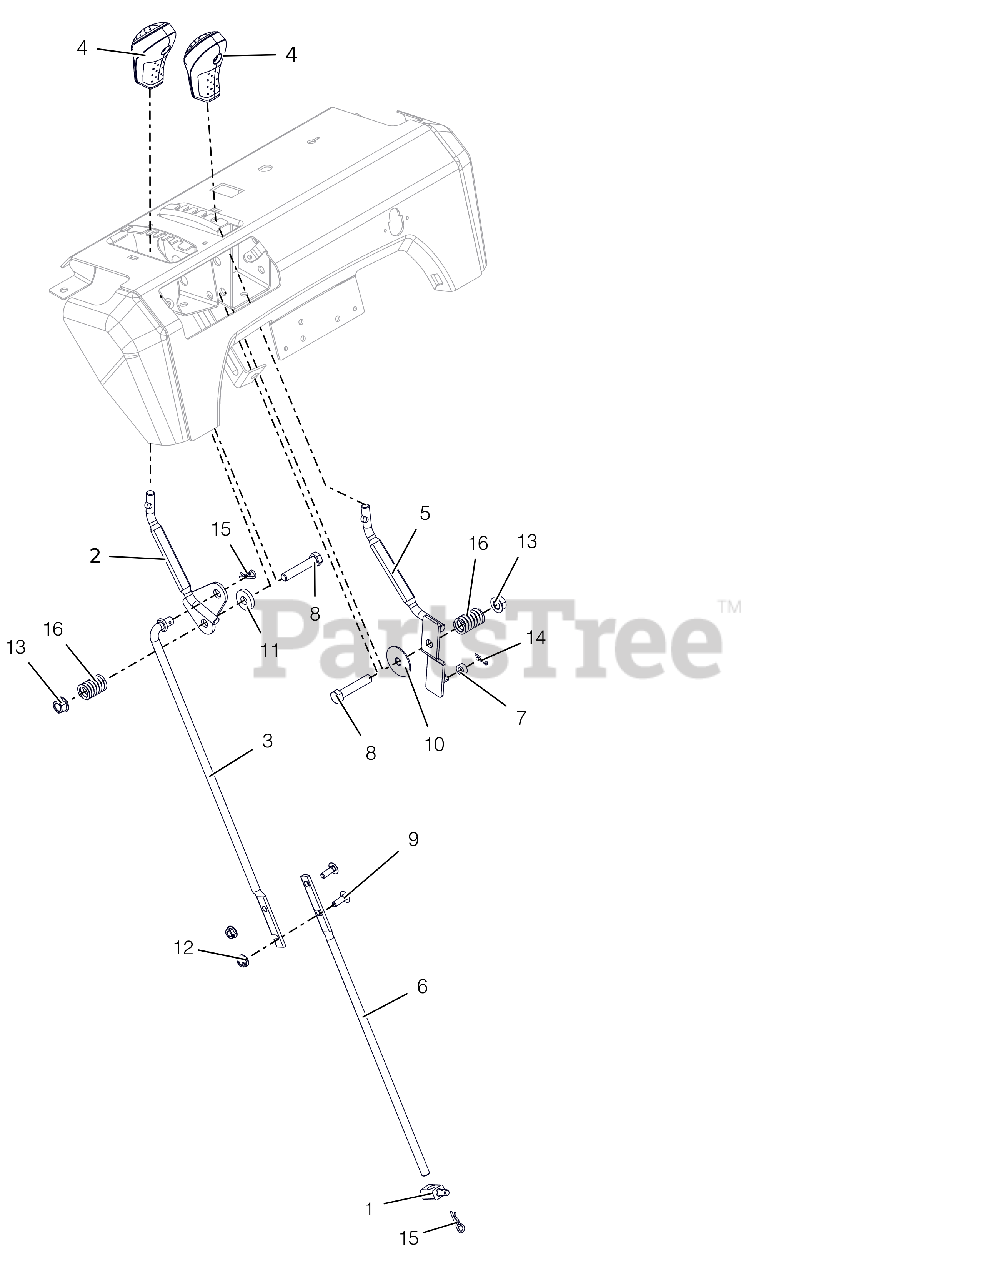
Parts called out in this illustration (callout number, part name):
1	PIVOT,SHIFT ROD .375-16(TRUNN)
2	WELDMENT,LG DASH SPEED CONTROL
3	ROD, SHIFT - UPPER
4	KNOB, CONTROL, DASH
5	WELDMENT,LG DASH DEFL CONTROL
6	ROD, SHIFT-LOWER (LG DASH DLX)
7	BSHG-SLV .265X.500X.219
8	@BLT-HEX .38-16X2.00 GR5 YWZC
9	@BLT-RDHDSQNK .25-20X.75 G5YZ
10	WSHR-FL-STL .380X1.50X.062 YWZ
11	WSHR-FL-STL .406X1.00X.188 YWZ
12	@NUT-LK-CTR-FLG .25-20 YWZC
13	@NUT-LK-TOP-FLG .38-16 YWZC
14	PIN-HAIR INT .06X.18X.77
15	PIN-HAIR INT .08X.18X1.18 YWZC
16	SG-COMP .125X.781X1.250
